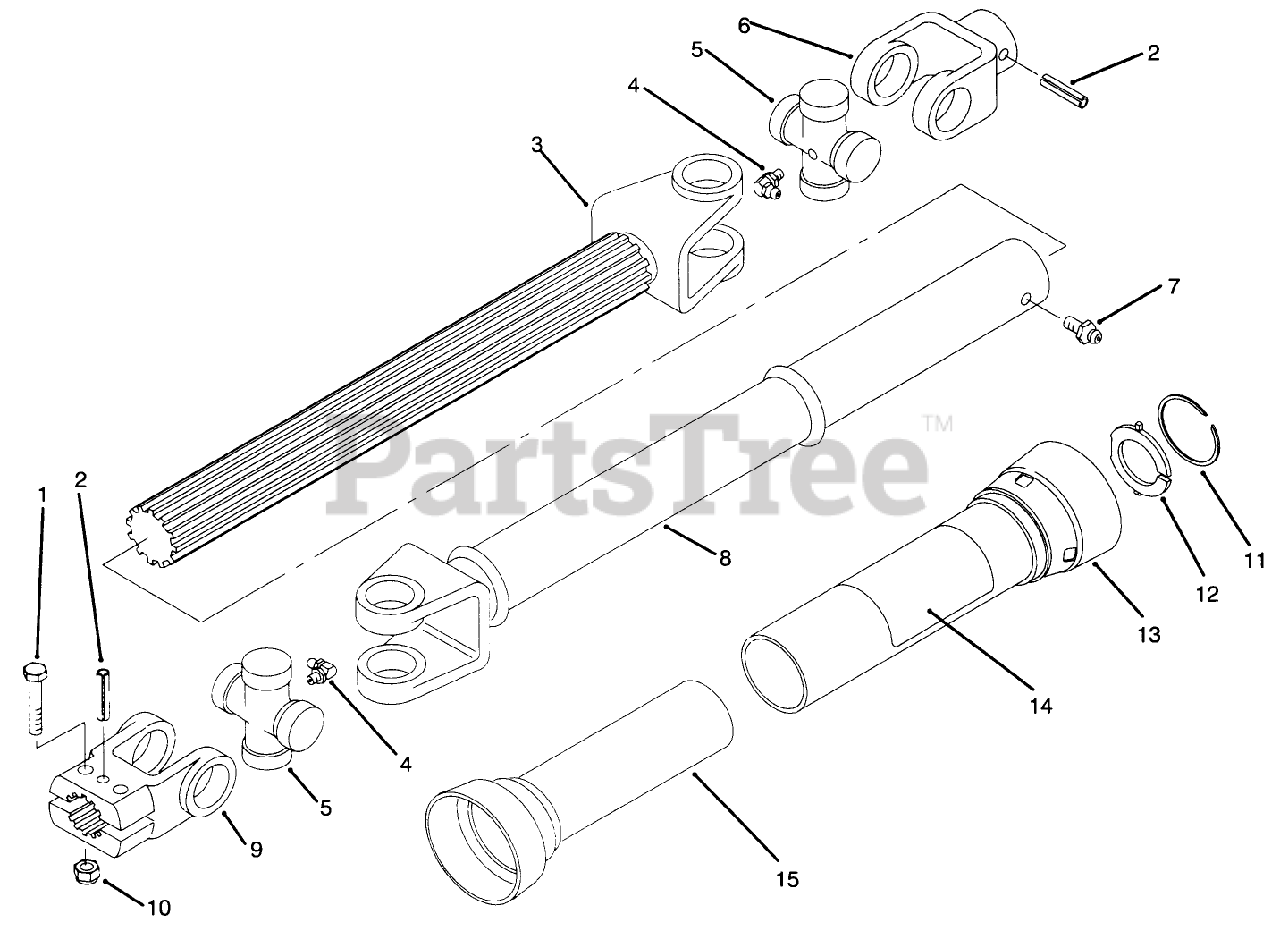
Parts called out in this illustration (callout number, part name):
1	SCREW-HH
2	PIN-ROLL
3	SHAFT-SLIP YOKE
4	FITTING-GREASE
5	U-JOINT KIT
6	YOKE-END
7	FITTING-STRAIGHT
8	TUBE-SLIP YOKE
9	YOKE-END
9	Yoke-End (Split)
10	NUT-LOCK, NI
11	RING-Retaining
12	Bushing-Nylon
13	Assembly-Guard, Outer (Incl. Ref. #11-12 & 14)
14	DECAL-DANGER
15	Assembly-Guard, Inner (Incl. Ref. #11-12)
